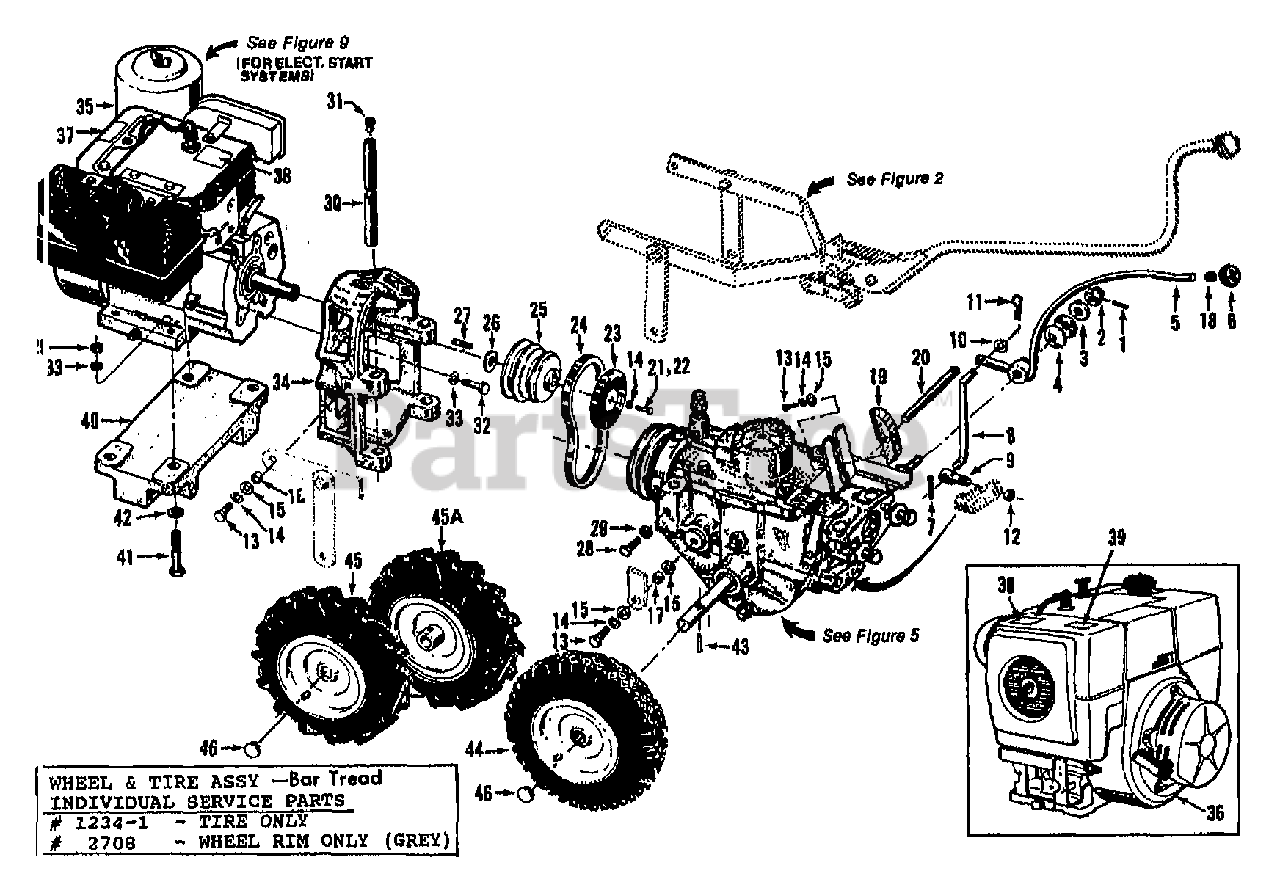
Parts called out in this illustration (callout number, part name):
1	PIN-SPRING .125 X 1
2	NUT-HEX 1/2-20
3	WASHER-# SHOULDER ZP (SHOULDER FACES DISC WASHERS)
4	WASHER-# 1.97X1X.118 (CONCAVE SURFACES FACE EACH OTHER)
5	LVR-W/KNOB (WHEEL SPEED)(INCL. 6 & 18)
6	KNOB-WHEEL SPEED HORSE (INCL. 18 & PLASTIC DECAL INLAY)
7	PIN-COTTER .094X1.0
8	ROD-CONNECTING
10	WASHER-FLAT 5/16 SAE
11	PIN-CLIP .08
12	NUT-H/LK 5/16-18
13	SCR-HH 3/8-16X1.0 G5 ZP
14	WASHER-LK .375
15	WASHER-FLAT 3/8 SAE
16	BUSHING-.5X.375X.325
17	BUSHING-.5X.375X.3
18	RING-TOLERANCE .5325 ID
19	KIT-ADJ BLOCK 4 SP (INCL. 13-15, & 20)
20	BAR-ADJUST
21	SCR-HH 3/8-24X1.75 ZP (FOR 7HP TEC. ENGINE ONLY)
22	SCR-HH 3/8-24X1.5 G5 (FOR KOHLER ENG. ONLY)
23	KIT-ADJ BLOCK/REV DISC (INCL. 19)
23	DISC-REV
25	PULLEY-ENG MACH (POWER TAKE OFF)
26	SHIM-1.0X.7656X.062
26	SHIM-1.0X.7656X.031
27	KEY-.188 SQ X 2.33
28	SCR-HH 5/16-18X1.0 G5 ZP
29	NUT-HEX 5/16-18 ZP
30	BAR-ENG MTG W/CAP PLUG
31	PLUG-CAP (RED)
32	BOLT-HH 5/16-24X1.125 G5 ZP
33	WASHER-LK .312 ZP
34	MOUNT-MOTOR HSE OPC PNT
35	ENGINE, 7HP TEC. - RECOIL START. MODEL NO. HMXL-70, SPEC NO. 132503.
35	ENGINE, 7HP TEC. - ELEC. START. MODEL NO. HMXL-70, SPEC NO. 132504.
36	ENGINE, 8HP KOHLER MAGNUM, RECOIL START, MODEL M8T, SPEC NO. PS-301548.
36	ENGINE, 8HP KOHLER MAGNUM, ELEC. START, MODEL M8T, SPEC NO. PS-301549.
37	DECAL-STABI 7HP OPC TRL
38	DECAL-HOT SURFACE
39	DECAL-STABIL STARTING
40	WEIGHT-ENG ECONO PNT
41	SCR-HH 5/16-18X2.25 G5ZP
42	SPACER-.88X.385X.09 ZP
43	PIN-SPIROL .313 X 1.5
44	ASSM-STD TIRE
45	TIRE-LT BT GARDEN TRAC
45A	TIRE-RT BT GARDEN TRAC
46	CAP-HUB BLK PLASTIC
